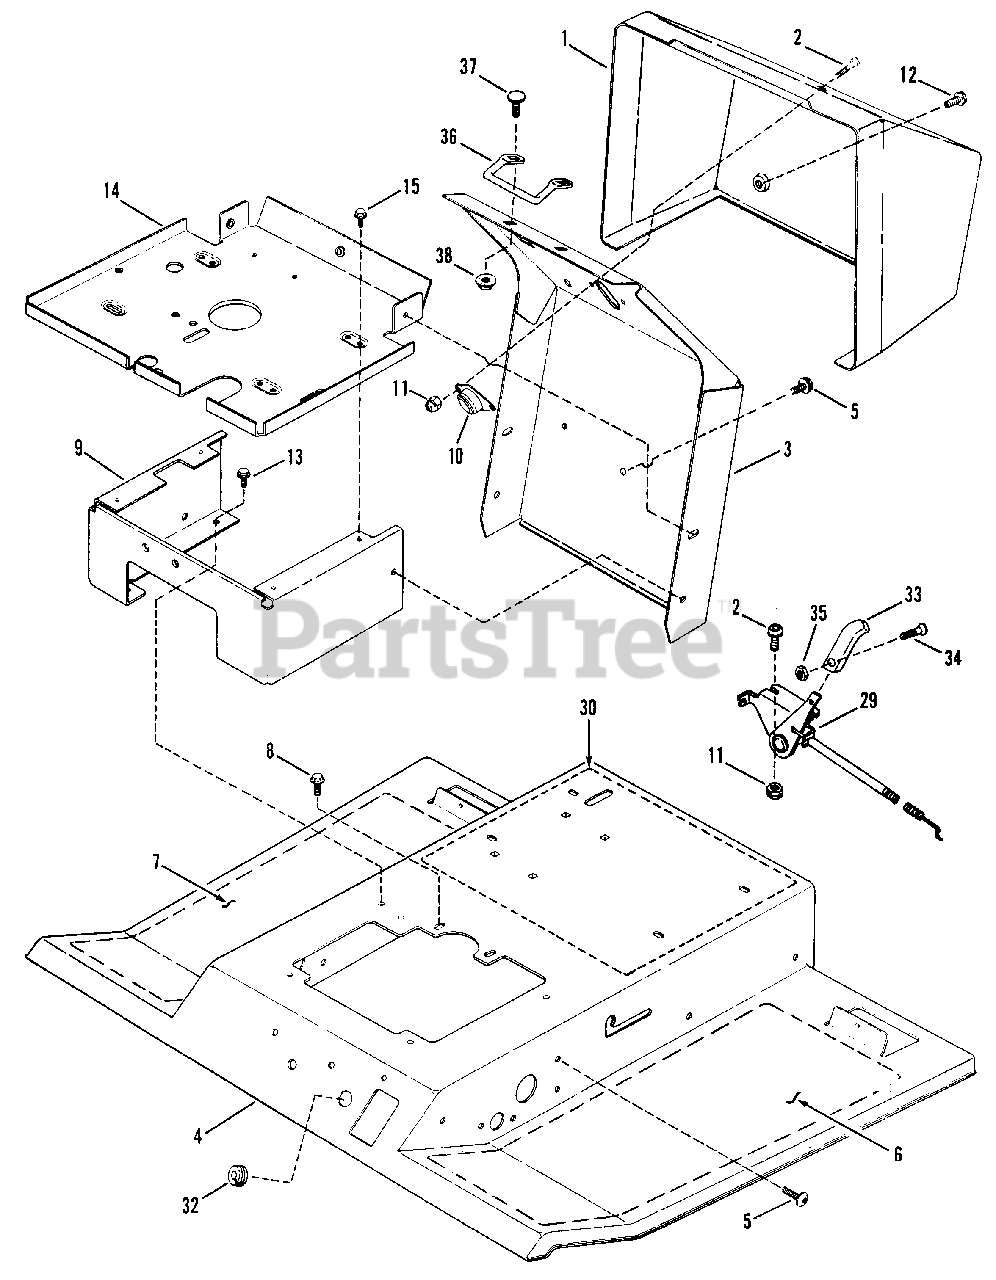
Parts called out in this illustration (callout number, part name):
1	PANEL, Dash
2	SCREW, 1/4-20 x 1" Phillips
3	SUPPORT, Steering Shaft
4	CHANNEL, Foot Rest
5	SCREW, 5/16-18 x 7/8" Torx, S.T.
6	TREAD, Left Side (Non-Skid)
7	TREAD, Right Side (Non-Skid)
8	SCREW, 5/16-18 x 5/8" Hex Cap S.T.
9	MOUNT, Fuel Tank/Battery
10	FLANGE ASSM'Y., Steering Shaft .75" ID Bearing
11	NUT, 1/4-20 Hex
12	SCREW, #10-24 x 1/2" Self-Tapping
13	SCREW, 5/16-18 x 1/2" Self-Tapping
14	PLATE, Fuel Tank & Battery Mount
15	SCREW, 1/4-20 x 1/2" Hex Cap, S.T.
29	CONTROL, Throttle 41.6" Long
30	DECAL, Caution & Instruction
32	GROMMET, 5/16 I.D. for .75 Hole (No Longer available)
33	HANDLE, Throttle Control
34	SCREW, #8-32 x 3/8" Recessed, Fillister Head
35	NUT, #8-32 Hex
36	ROD, Hood Latch (No longer available, try using 7033828)
37	BOLT, 1/4-20 x 5/8" Flat Head Carriage
38	NUT, 1/4-20 Hex Flange Lock
